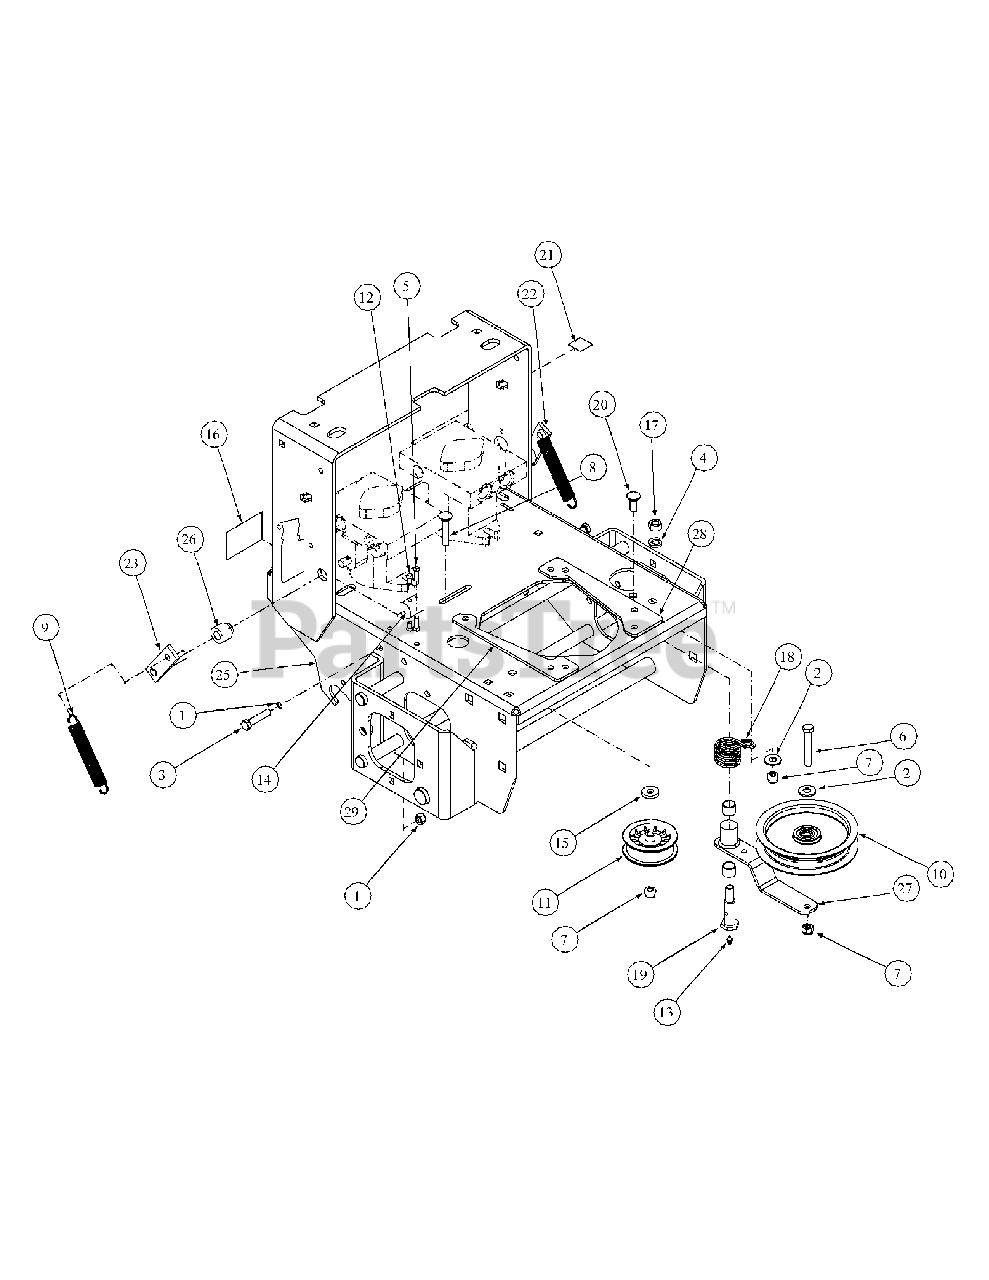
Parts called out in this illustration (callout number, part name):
1	Hex Nut, 3/8-16
2	Flat Washer, 3/8
3	Capscrew, 3/8-16 x 1-3/4
4	Lock Washer, 7/16
5	Cap Screw, Square Head Set, 1/4-20
6	Hex Cap Screw, 3/8-16, 2.50
7	Lock Nut, Nylon Insert, 3/8-16
8	Carriage Bolt, 3/8-16 x 2
9	Wire Spring
10	Deck Idler Take-up
11	Flat Idler Pulley, with Adaptor
12	Cap Screw, Square Head Set , 1/4-20
13	Grease Fitting, 1/4-28 x 3/16
14	Trunnion, Coupling
15	Idler Washer
16	Decal, Made In America
17	Hex Nut, 7/16-14
18	Idler Torsion Spring
19	Shoulder Bolt
20	Carriage Bolt, 3/8-16 x 1
21	Label, Warning Mower
22	Hydro Pump Lever Assembly, LH
23	Hydro Pump Lever Assembly, RH
25	Engine Base Assembly
26	Pump Lever Bushing
27	Idler Bracket Assembly w/Bearings
28	Engine Spacer, RH
29	Engine Spacer, LH
